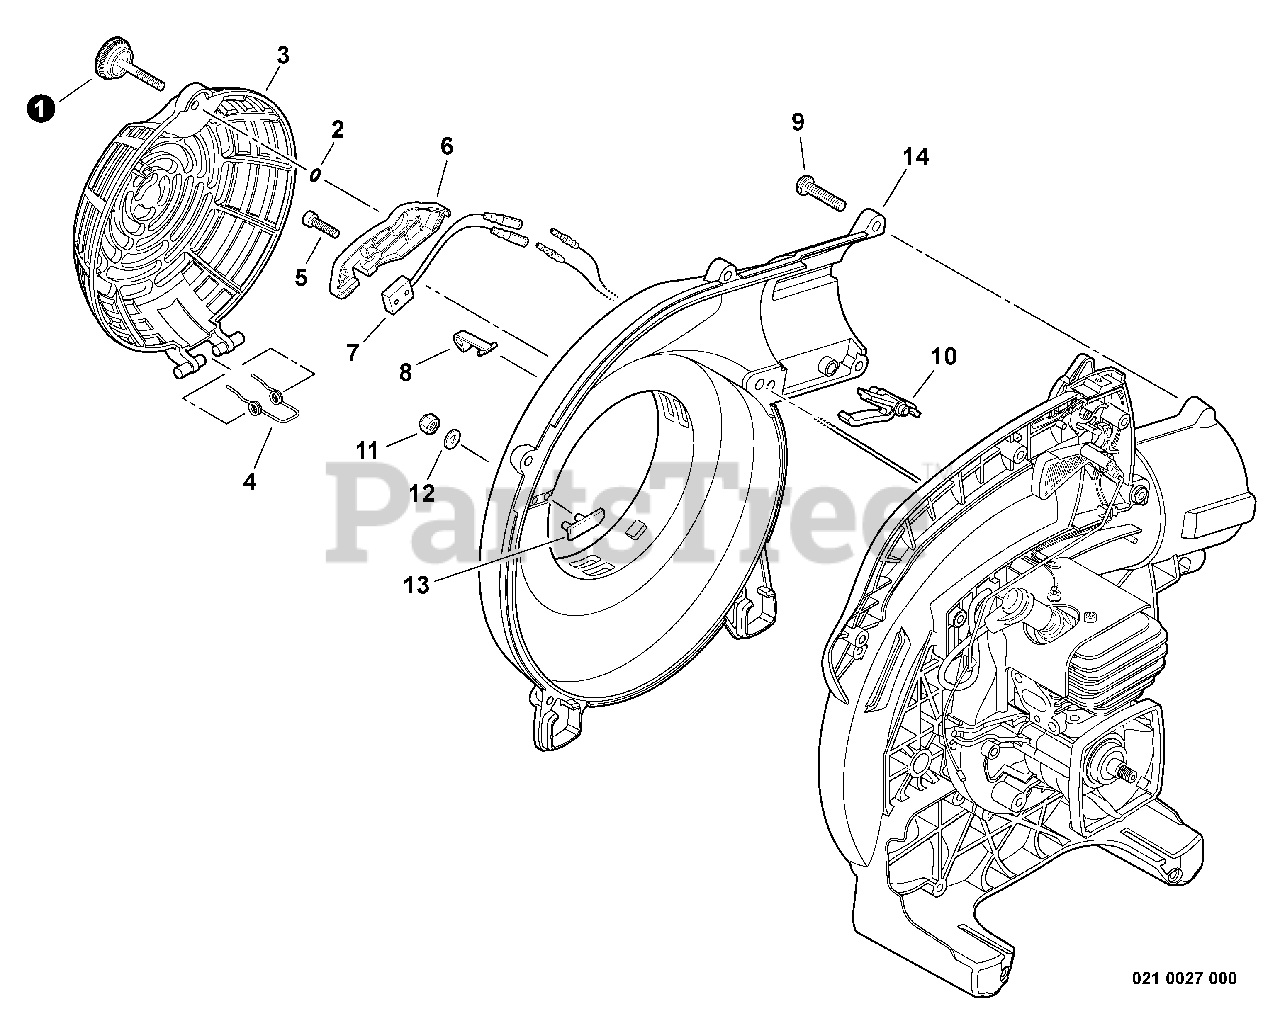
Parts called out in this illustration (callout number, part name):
1	THUMBSCREW
2	O-RING 3
3	GUARD, FAN
4	SPRING, TORSION
5	BOLT, TORX 4×16
6	COVER, SWITCH
7	SWITCH, SAFETY
8	LEVER, ACTUATOR
9	BOLT, TORX 5×20
10	LOCK, TUBE
11	NUT, LOCK M5
12	WASHER 5.5×12×0.8
14	COVER, FAN
